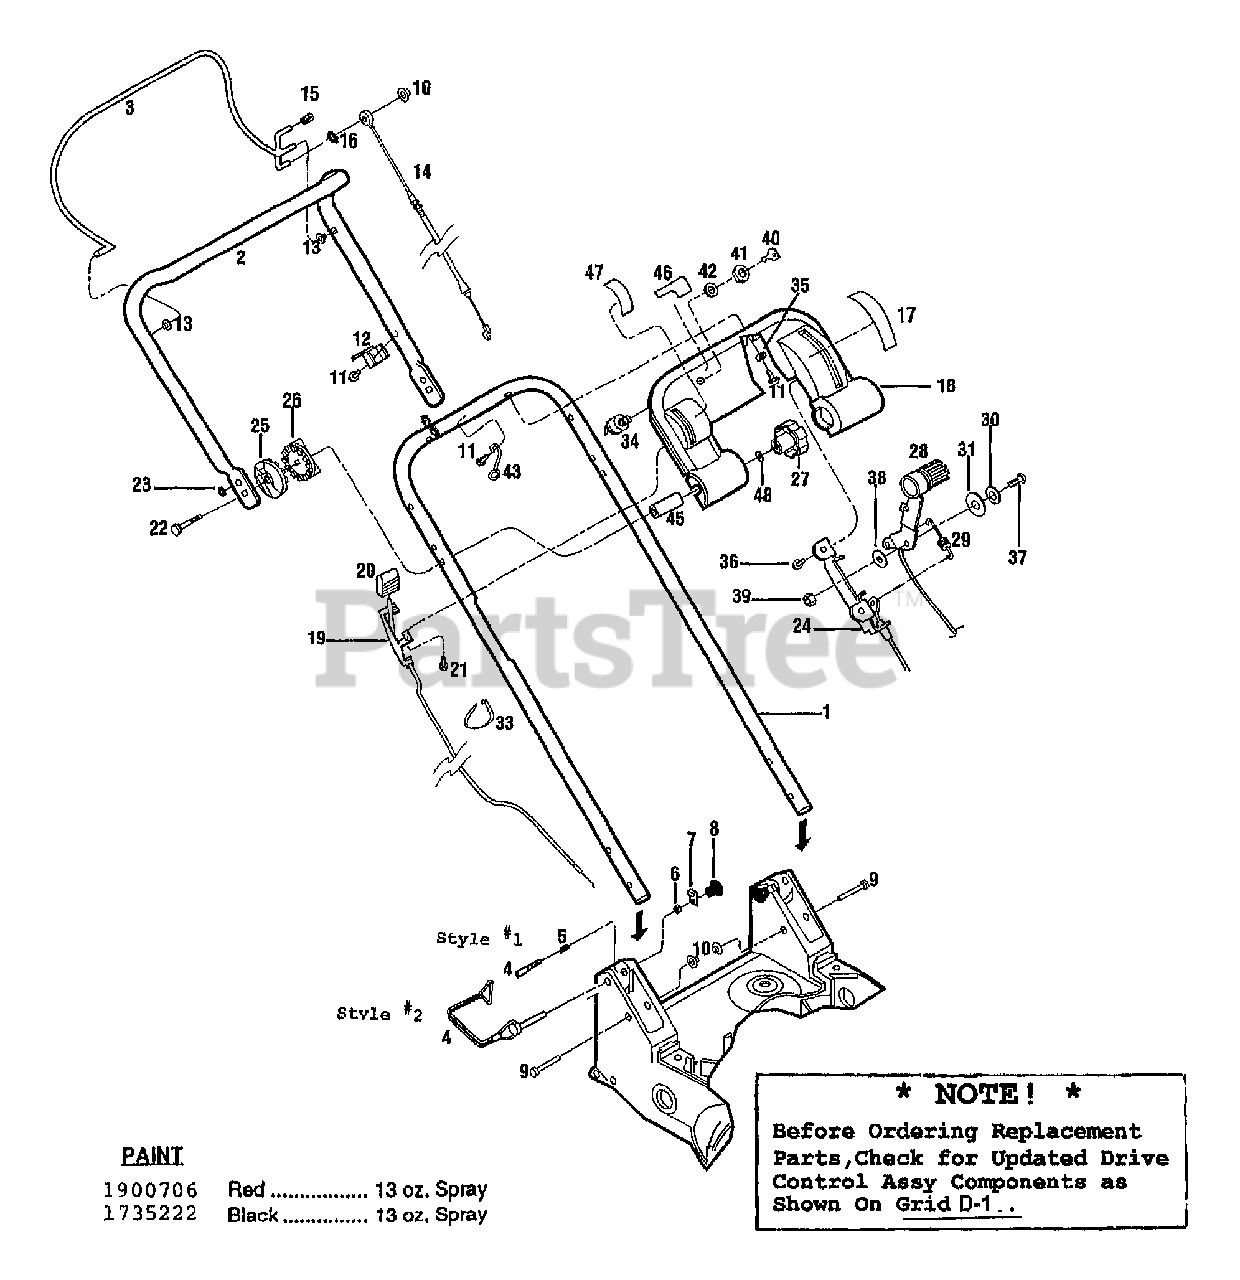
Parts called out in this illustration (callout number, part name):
1	HANDLEBAR-LOWER
1	HANDLEBAR-LOWER PNT
2	HANDLEBAR-UPR PNT
3	BAIL-CONTROL VINYL COATED
4	PIN-STOP
4	PIN-LK SQ. #W51620LP
5	SPRING-COMPRESSION
6	NUT-HEX 1/4-20 ZP
7	ARM-STOP ZP BLACK CHRMATE
8	KNOB
9	PIN-CLEVIS ( @DEPL)
10	CAP-PUSH .312
11	SCR-FLANGE 1/4-20X3/4 GR5
12	BRKT-CONTROL CABLE
13	BUSHING-PLASTIC (BAIL)
14	CABLE-ENGINE BRAKE
15	CAP-PLASTIC (BAIL)
16	GRIP-RING EXT .312 ID
17	DECAL-WHEEL DRIVE
18	CONSOLE-HANDLEBAR
19	CABLE-THROTTLE
20	KNOB-WHEEL DRIVE CABLE
21	SCR-M10-16X.88 SPECIAL
22	SCR-CARR 5/16-18X4.56
23	RETAINER .25
24	CABLE-CLUTCH
25	QUADRANT-OUTER (WAS 1767425)
26	KIT-QUADRANT INNER (WAS 1767375)
27	KNOB-HANDLE ADJUST
28	KIT-DRIVE CABLE MULCHER
29	SPRING-EXTENSION
30	WASHER-BELLEVILLE
31	WASHER-1.0X.25X.06 ZP
33	TIE-CABLE, REUSABLE
34	SWITCH-EL IGNITION (INCL. 40-42)(MODEL 34023)
35	WASHER-FLAT, .265 I.D.
36	SCR 1/4-15X.88 SPECIAL
37	SCR-RH 1/4-20X.75
38	BUSHING-NYLON
39	NUT-HT LK 1/4-20
40	KEYS-IGN T/BLAZER 1 PAIR (MODEL 34023)
41	NUT-HEX/JAM 5/8-32 ZP(MODEL 34023)
42	WASHER-LK 5/8 INT TOOTH (MODEL 34023)
43	GUIDE-ROPE
46	DECAL-ELEC START (MODEL 34023)
47	DECAL-THROTTLE
48	WASHER-#.75X.32X.09 ZP
